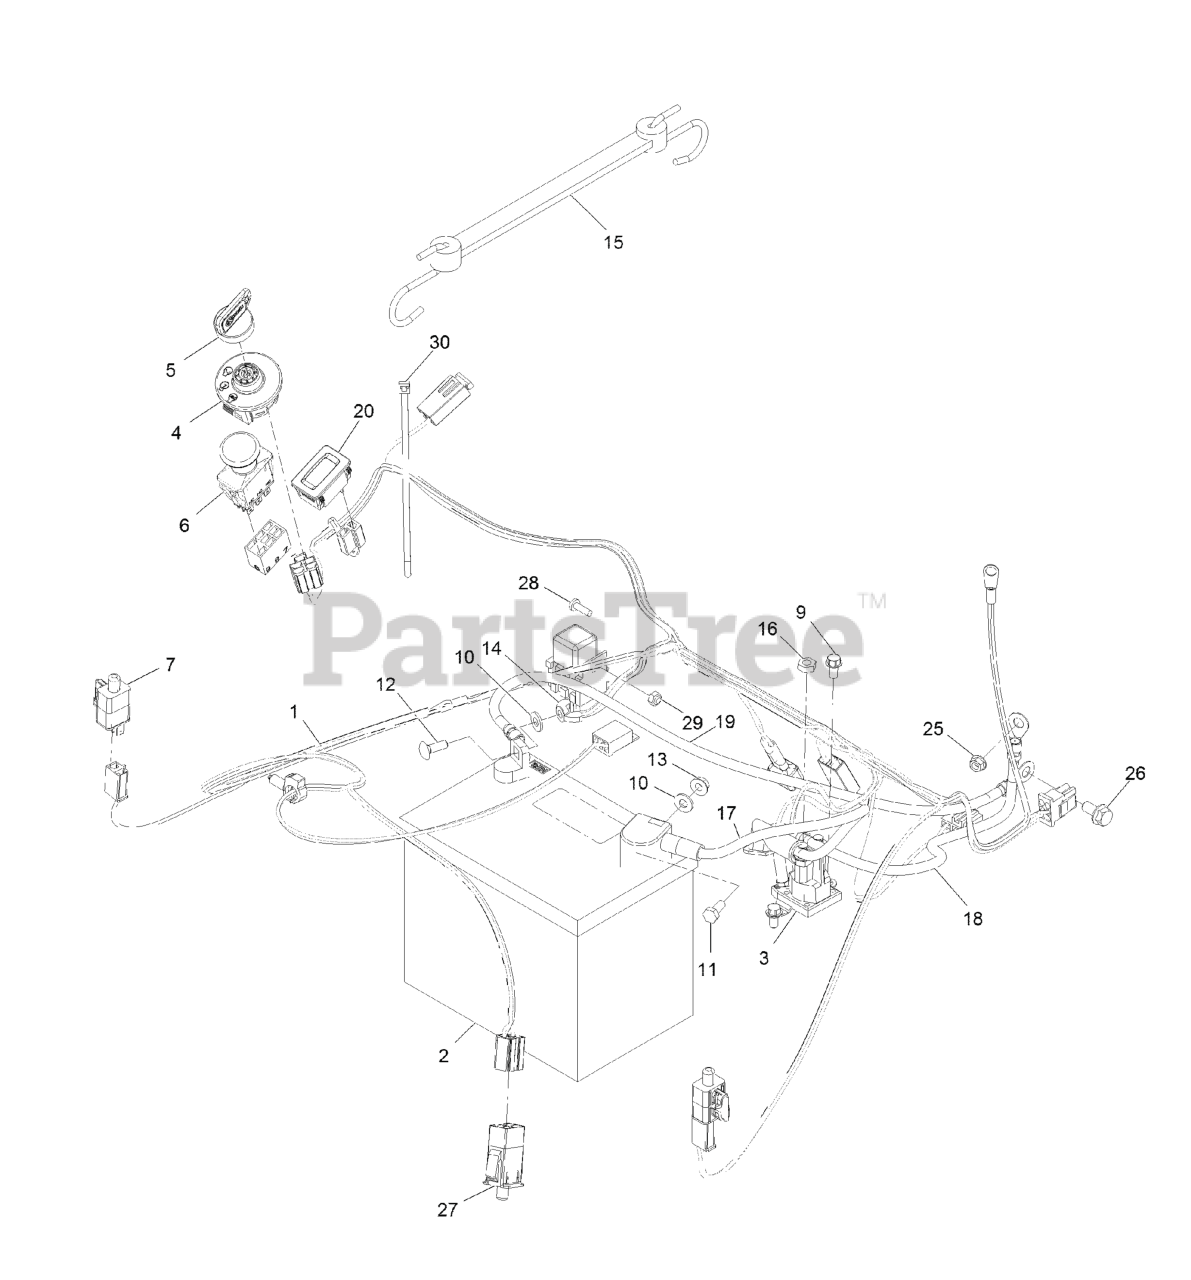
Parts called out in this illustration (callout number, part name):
1	HARNESS-WIRE
2	BATTERY
3	SOLENOID
4	SWITCH-IGNITION
5	KEY-IGNITION
6	SWITCH-PTO
9	SCREW-HWH
10	WASHER-FLAT
11	SCREW-HH
12	BOLT-CARR
14	NUT-WING
15	HOLDDOWN-BATTERY
16	NUT-JAM
17	CABLE-BATTERY, RED
18	CABLE-BATTERY, POSITIVE
19	CABLE-BATTERY, BLACK
20	HOURMETER
26	SCREW-HHF
27	SWITCH-DELTA
28	SCREW-PPH
29	NUT-LOCK, NI
30	TIE-CABLE
